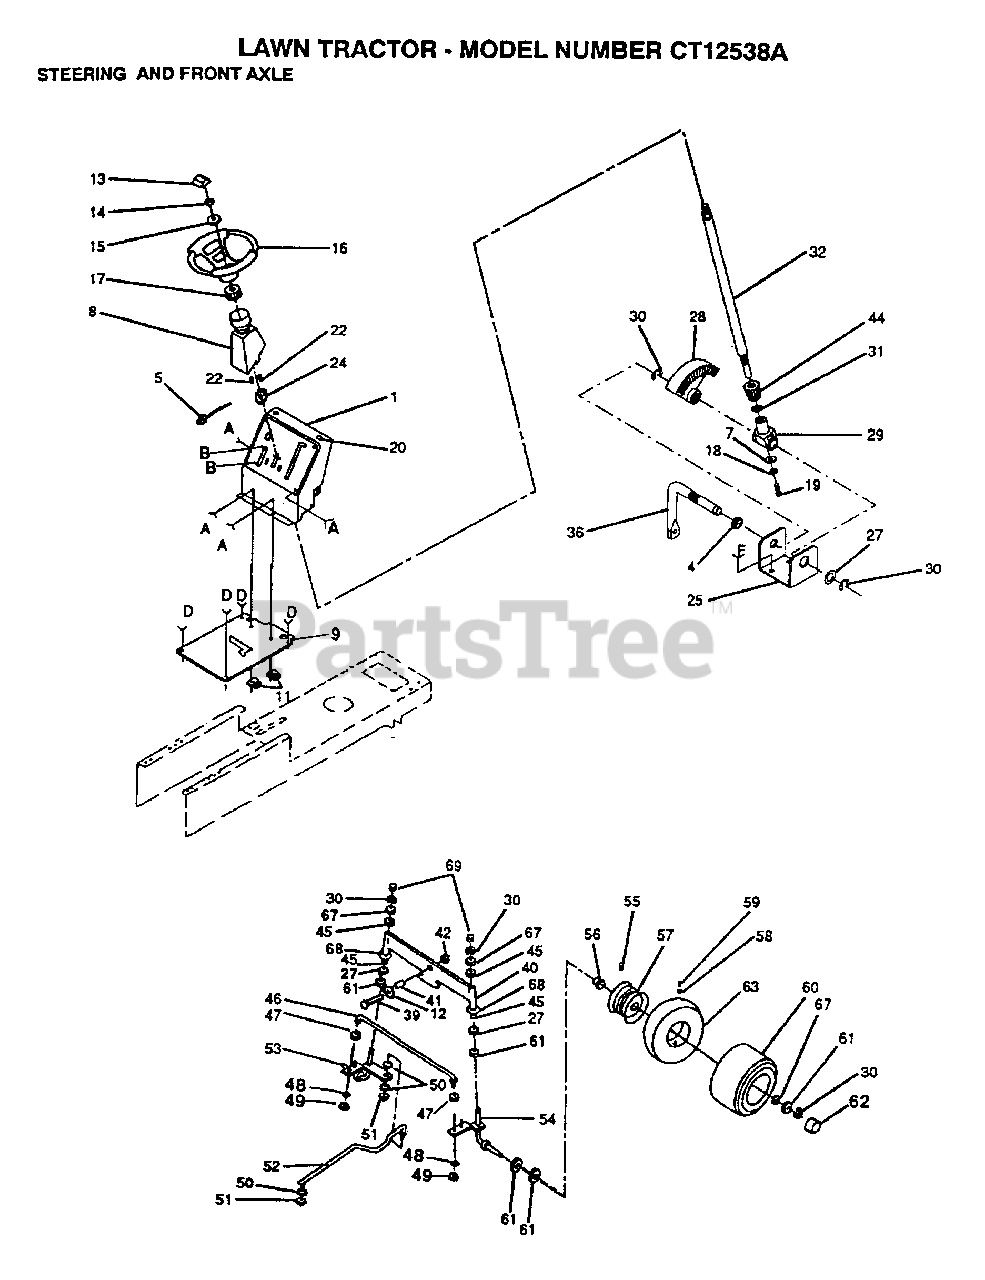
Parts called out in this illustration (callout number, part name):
4	NYLINER T
8	"TUBE, STR SHAFT"
13	INSERT-WHEEL LT
15	WASHER
17	ADAPTER LT
18	LOCKWASHER
19	"SCREW,SPECIAL"
24	"BUSHING,STEERING"
25	"BRKT,STEERING"
27	WASHER .T
29	SUPPORT.SHAFT
30	RING
31	THRUST WASHER
39	BOLT LT
41	BEARING
42	"NUT-LOC,FLANGE LT"
44	"GEAR,PINION"
45	COL. SRTG. BEAR.
46	ROD TIE
47	WASHER M
48	LOCKWASHER
49	NUT.LOCK.5/16-24
50	LOCKWASHER
53	SPINDLE-LH LT
55	FITTING LT
56	"FLANGE, BEARING"
58	VALVE CAP
59	VALVE STEM LT
61	WASHER
62	HUB CAP
63	TUBE.5.3/4.5/6
67	WASHER
68	WASHER
69	CAP
